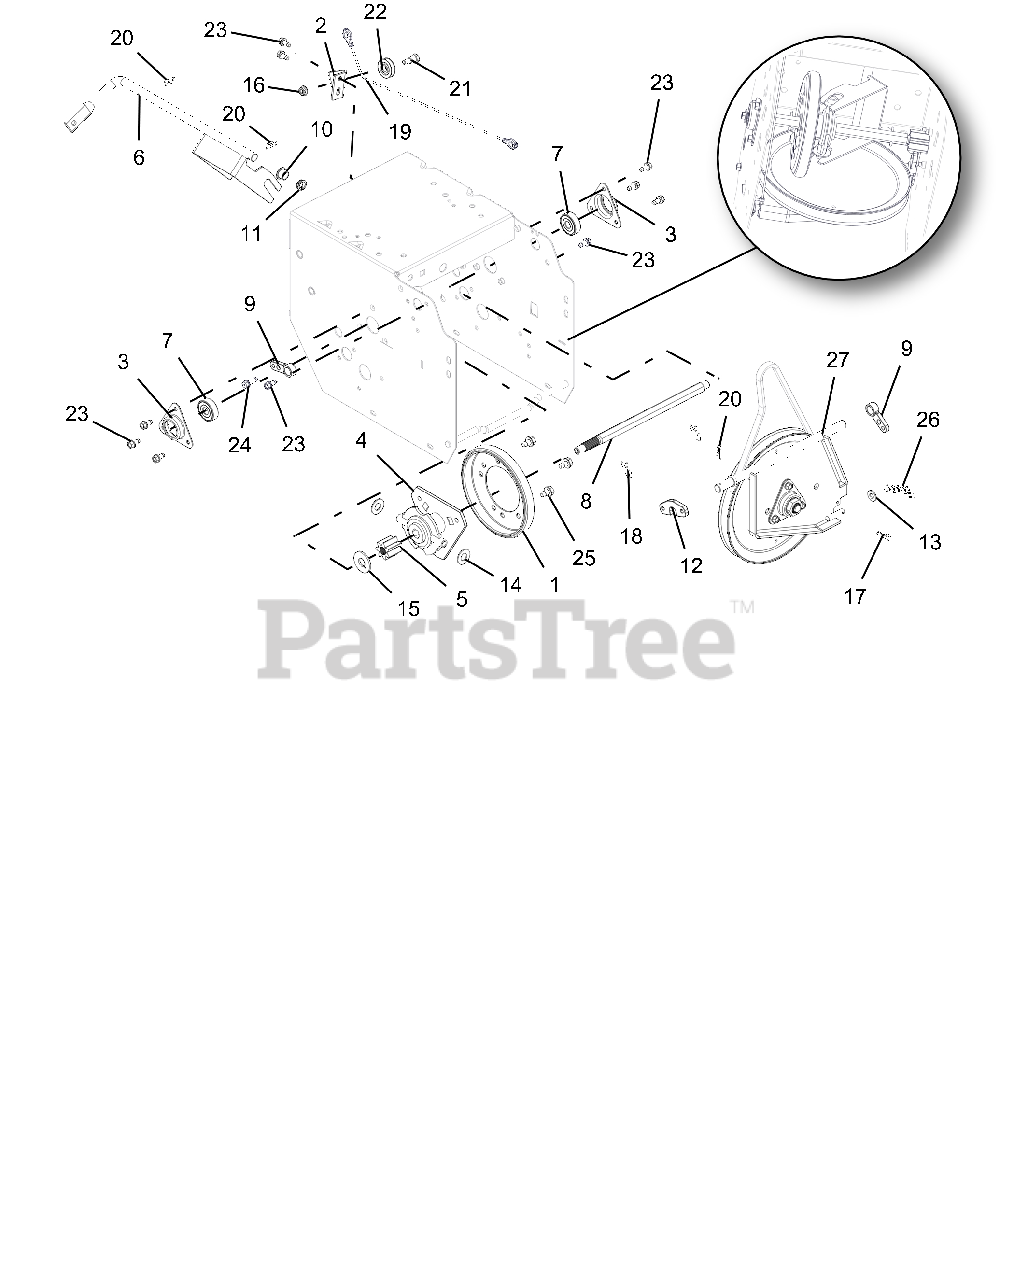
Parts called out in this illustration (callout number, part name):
1	FRICTION, DISC
2	BRACKET, CABLE PULLEY
3	FLANGE, BEARING
4	CARRIER, DRIVE DISK
5	GEAR, PINION, 7 TOOTH W/SPLINE
6	WELDMENT, SHIFT FORK
7	BRG-BALL .437X1.375X.437
8	SHAFT, HEX W/SPLINE
9	SUPPORT BUSHING, SWING GATE
10	BUSHING, POLYLINER-.50 SPLIT
11	BUSHING, POLYLINER-.50 SNAPIN
12	SPACER, SWING GATE
13	@WSHR-FL-STL.344X.688X.065YWZC
14	WSHR-FL-STL .505X1.00X.062YWZC
15	@WSHR-FL-STL.563X1.38X.109YWZC
16	@NUT-LK-CTR-FLG .25-20 YWZC
17	PIN-HAIR INT .08X.18X1.18 YWZC
18	PIN, SPRING CLIP
19	CABLE, LOWER TRACTION (CMPCT)
20	CLIP, SPRING
21	BOLT, SHLDR-.375X.375X.25-20
22	PULLEY, CABLE
23	SCR-TAP .25-20X.50 HWH TR YWZ
24	SCR-TAP-PM .25-20X.75 TR YWZ
25	@SCR-TAP .31-18X.50 HWH TR YWZ
26	SPRING, EXT. .043X.438X1.64
27	PLATE, SWING - ASSEMBLY
